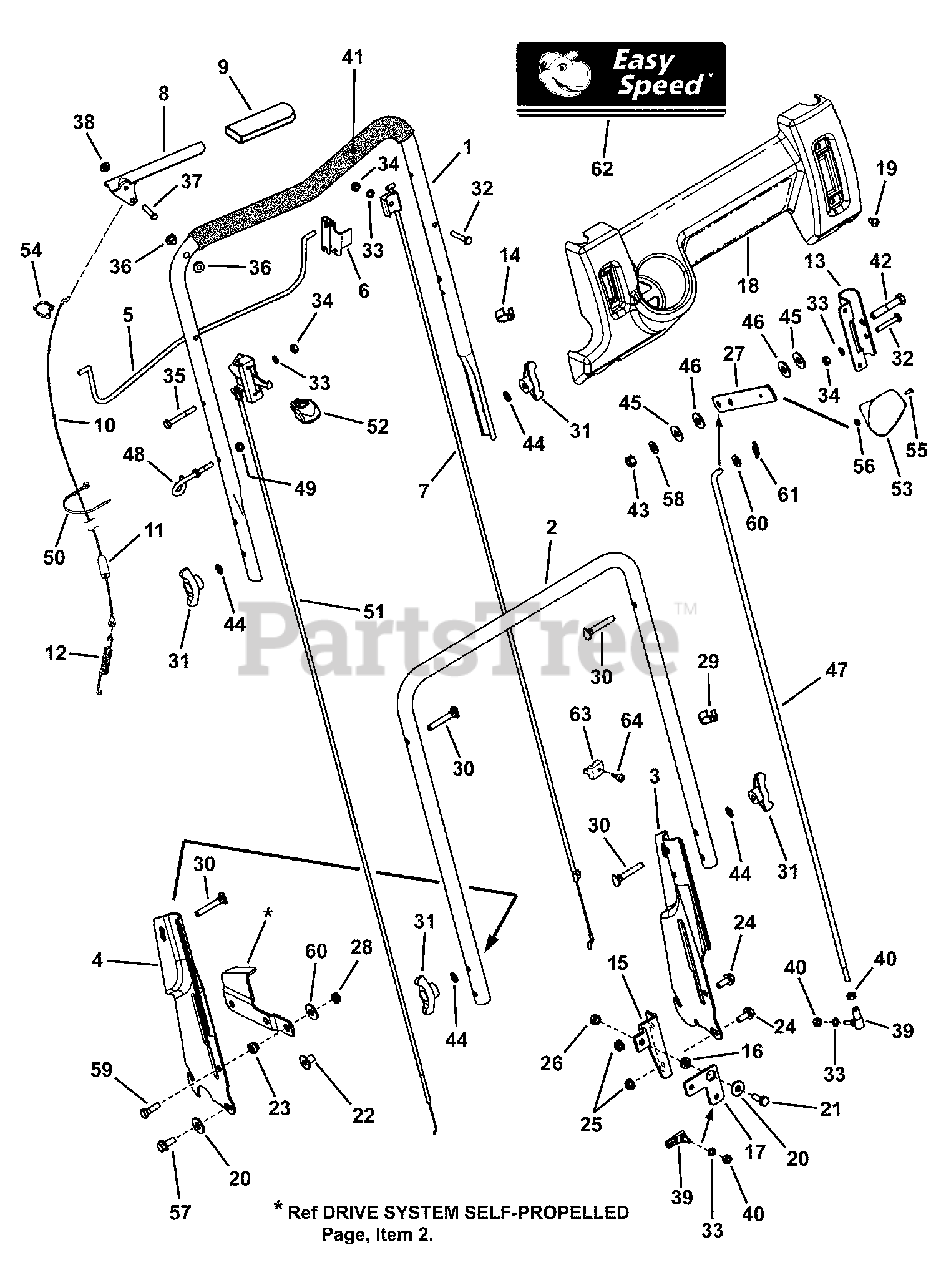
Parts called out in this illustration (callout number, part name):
1	HANDLE, Upper
2	HANDLE, Middle
3	HANDLE, Lower LH (Adjustable)
4	HANDLE, Lower RH (Adjustable)
5	BAIL, OPC Control
6	CLIP, Zone Control
7	CABLE, Zone Control (53-63/64" Long)
7	CABLE, Zone Control (46-1/4" Long)
8	HANDLE, Clutch
9	GRIP, International Symbol
10	CABLE, Clutch Control (41-1/4" Long)
11	COVER, Vinyl
12	SPRING, Clutch- 21S
13	BRACKET, Shift
14	TIE, Wire, 1.29 long, black
15	BRACKET, Bell Crank
16	SPACER, .33 x .63 x .156
17	BELL CRANK
18	CONTROL PANEL (w/o Electrical Switch Hole)
19	SCREW, 1/4-20 x 1/2" Pan Head Self-Tap (Torx)
20	WASHER, .33 x .88 x .09 Flat
21	SCREW, 5/16-18 x 7/8" Hex Head Cap, GR 5
22	TEENUT, 5/16-18
23	BUSHING, Differential, .328 x .625 x .41
24	BOLT, 5/16-18 x 3/4" Hex Flange Lock GR 5
25	NUT, 5/16-18 Hex Flange Lock, GR 5
26	NUT, 5/16-18 Hex Center Lock
27	LEVER, Shift
28	NUT, 5/16-24 Hex Center Lock GR 5
29	CLIP, Wiring Harness
30	SCREW, 5/16-18 x 1-7/8" Curved Head GR 2
31	KNOB, 5/16-18 Wing (Black)
32	SCREW, 1/4-20 x 1-1/2 Hex Head Cap GR 5
33	WASHER, 1/4" Internal Tooth Lock
34	NUT, 1/4-20 Hex
35	SCREW, 1/4-20 x 2" Hex Head Cap, GR 5
36	BUSHING, .27 x .35 x .4 Flange
37	PIN, 1/4 x 1-1/2"
38	PUSH-NUT, 1/4"
39	BALL JOINT, 1/4-28
40	NUT, 1/4-28 Hex
41	FOAM GRIP, 18.75" long
42	SCREW, 3/8-16 x 2" Hex Head Cap, GR 5
43	NUT, 3/8-16 Hex Center Lock
44	WASHER, 5/16" Internal Tooth Lock
45	WASHER, 7/16" Flat
46	WASHER, Nylon
47	ROD, Speed Control (1/4-28 thread)
48	GUIDE, Rope (1/4-20 thread)
49	NUT, 1/4-28 Hex GR 5 or B
50	CABLE-TIE, 7"
51	* THROTTLE CONTROL, (48.5" long)
51	* THROTTLE CONTROL, (62.0" long)
52	THROTTLE KNOB
53	KNOB, Shift
54	CLAMP, 7/8" Double Cable
55	SCREW, #8-32 x 1/2" Cross Recess Filister Head Machine
56	NUT, #8-32 Hex
57	SCREW, 5/16-18 x 1-1/4" Hex Washer Head Self-Tap
58	WASHER, Belleville
59	SCREW, 5/16-24 x 1" Hex Head Cap GR 5
60	WASHER, 11/32" Flat
61	COTTER PIN, 5/16 Self Lock
62	DECAL, Easy Speed, Control Panel
62	DECAL, EZ Speed, Control Panel
63	CLAMP, Casing
64	SCREW,#10-32 x 5/8" Self-Tap
